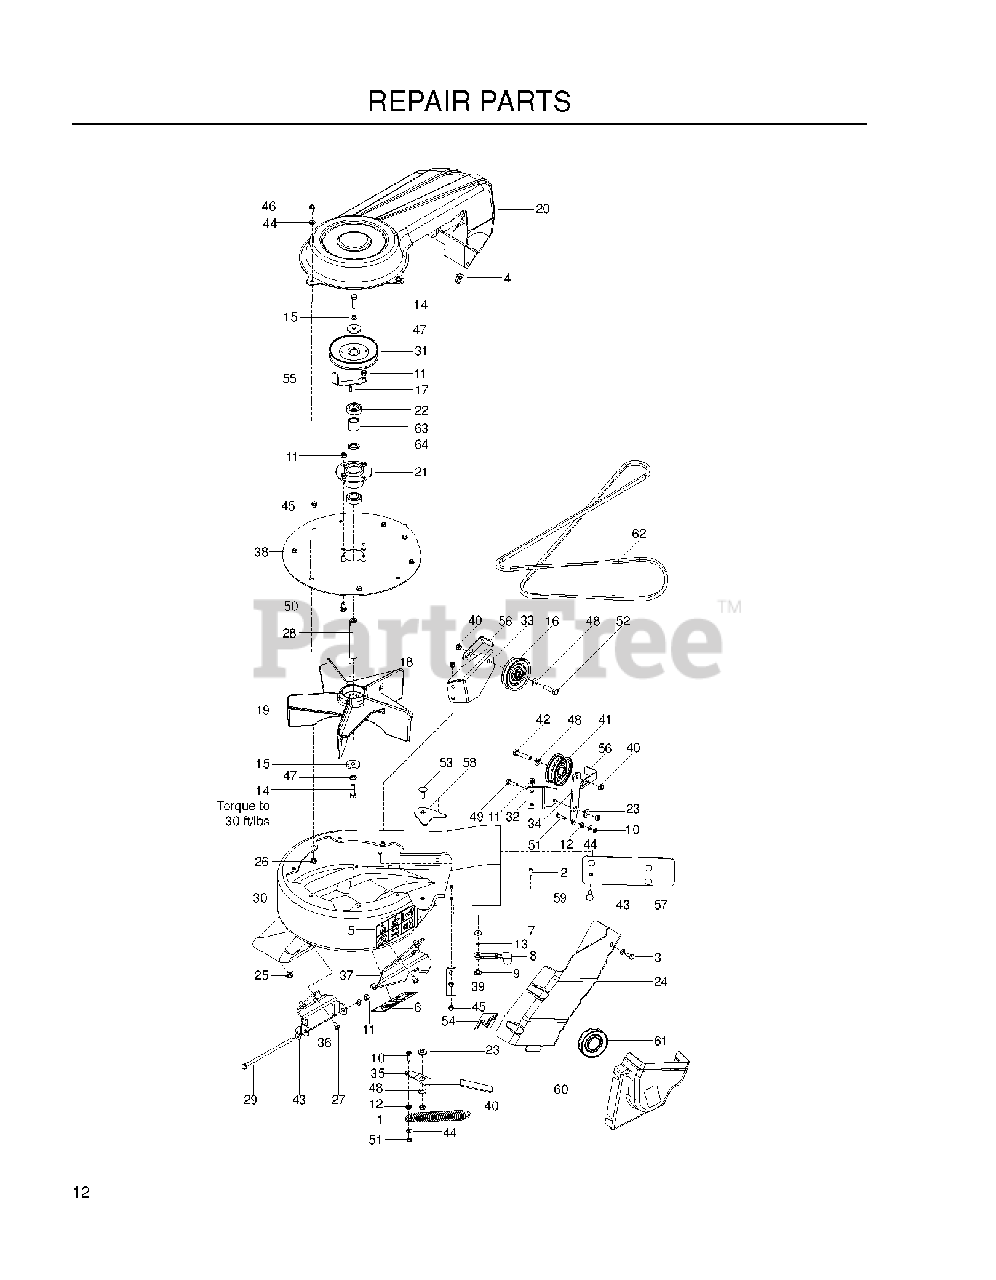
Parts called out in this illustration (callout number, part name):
2	SCREW #10-24 X 5/8
3	HCS 5/16C X 3/4
4	U-CLIP 5/16-18 NUT RETAINER
5	DECAL, EURO WARNING
6	EURO DECAL, IMPELLER
8	HOOD LATCH
9	NUT 10-24 WELD PLATED
10	JAM NUT 1/4C
11	NUT 5/16 NYLOC
12	NUT 1/4-20 HEX FLG LK ZD
13	WASHER - 3/16 LOCK ZD
14	BOLT, HEX 3/8-24 X 1.25 GR 8
15	WASHER, HARDENED
16	V-IDLER
17	KEY, 3/16 X 1/2
18	KEY-SQ. 3/16 X 1 1/2
19	IMPELLER.COLLECTION.BLOWER.BLA
20	COVER, BELT
21	HUB, BEARING
22	BEARING
23	BUSHING
24	COVER, BELT
25	NUT 5/16-18 TEE
26	NUT 1/4-20 TEE
27	HCS 5/16-18 X 1/2 GR 5 ZD
28	SHAFT, IMPELLER
29	BOLT - 5/16 X 7
30	BLOWER.HOUSING.W/DECALS.COLLEC
32	MOUNT, IDLER, UPPER
33	MOUNT, IDLER, LOWER
34	ARM, IDLER
35	ARM, TENSION
36	BRKT, MT, FRONT
37	BRKT, MT, REAR
38	PLATE, OUTER
40	NUT HEX 3/8-16 NYLON, THIN
41	IDLER PULLEY
42	BOLT, HCS 3/8-16X1-3/4
43	FLAT WASHER 5/16 SAE
44	WASHER 1/4 SAE
45	HWST 1/4C X 3/8
46	BOLT 1/4-20 X 1/2 HWST
47	SLW 3/8 STD
48	WASHER 3/8 SAE FLAT
49	HCS 5/16C X 1
50	BOLT 5/16C X 3/4" CARRIAGE
51	HCS 1/4-20X7/8 GR5
52	HCS 3/8C X 1 1/2
53	RHSNB 3/8C X 1
54	DECAL, BELT ROUTING
55	KEEPER, BELT, OUTER
56	KEEPER, BELT, REAR
57	PLATE.BACKING.BLACK
58	PLATE, BACKING
59	RHSNB 5/16C X 1
60	SHIELD, BELT, 42
61	PULLEY, 42
64	WASHER .787 X 1.125 X .06
